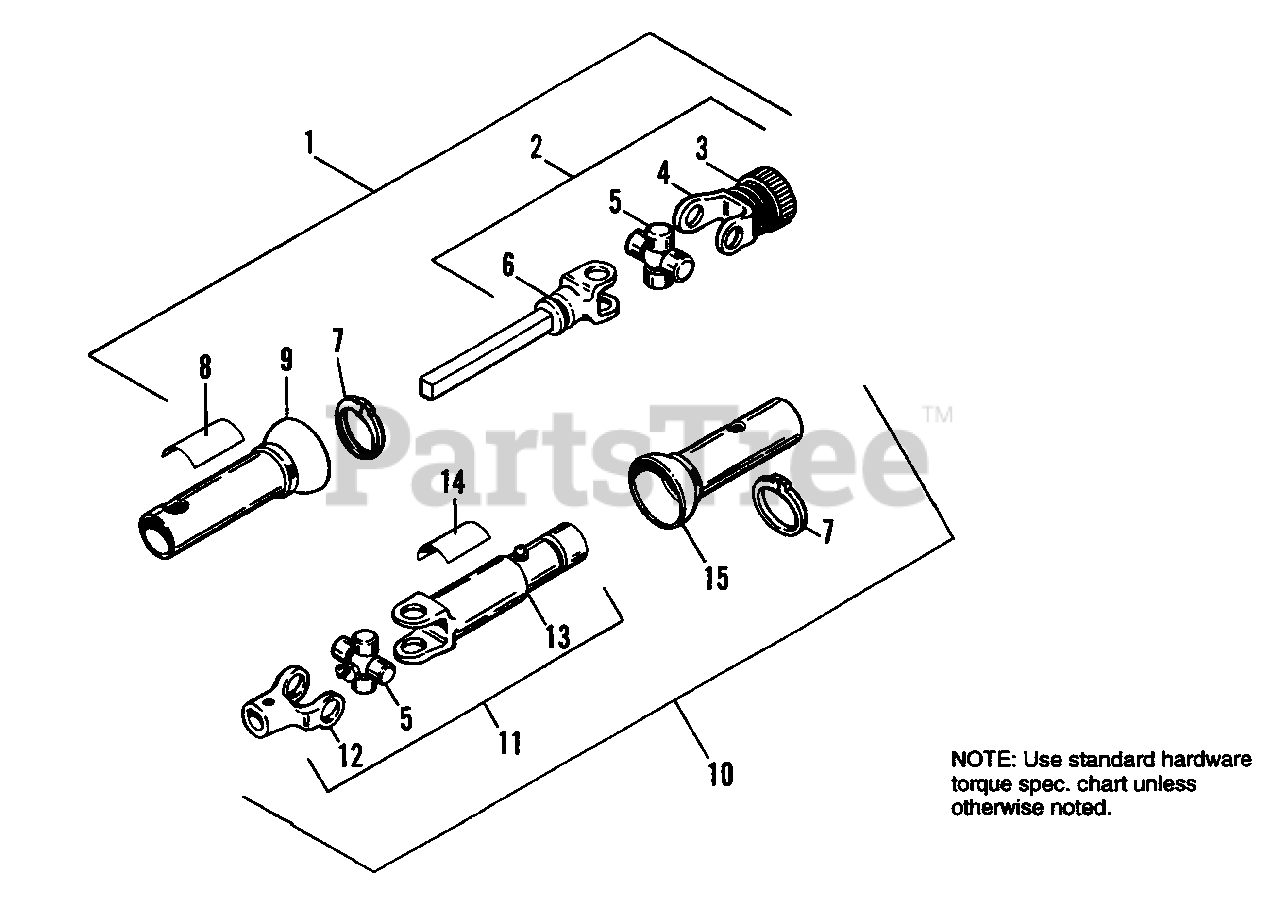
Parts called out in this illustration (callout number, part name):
1	JOINT & SHAFT ASSY., w/guard
2	JOINT & SHAFT ASSY.
3	SPRING-LOK REPAIR KIT
4	SPRING-LOK YOKE ASSY.
5	CROSS & BEARING KIT
6	YOKE & SHAFT ASSY.
7	REPAIR KIT, Nylon
8	DECAL, Warning
9	GUARD, Outer
10	JOINT & TUBE ASSY., w/guard
11	JOlNT & TUBE ASSY.
13	YOKE TUBE & SLIP SLEEVE ASSY.
14	DECAL, Warning
15	GUARD, Inner
